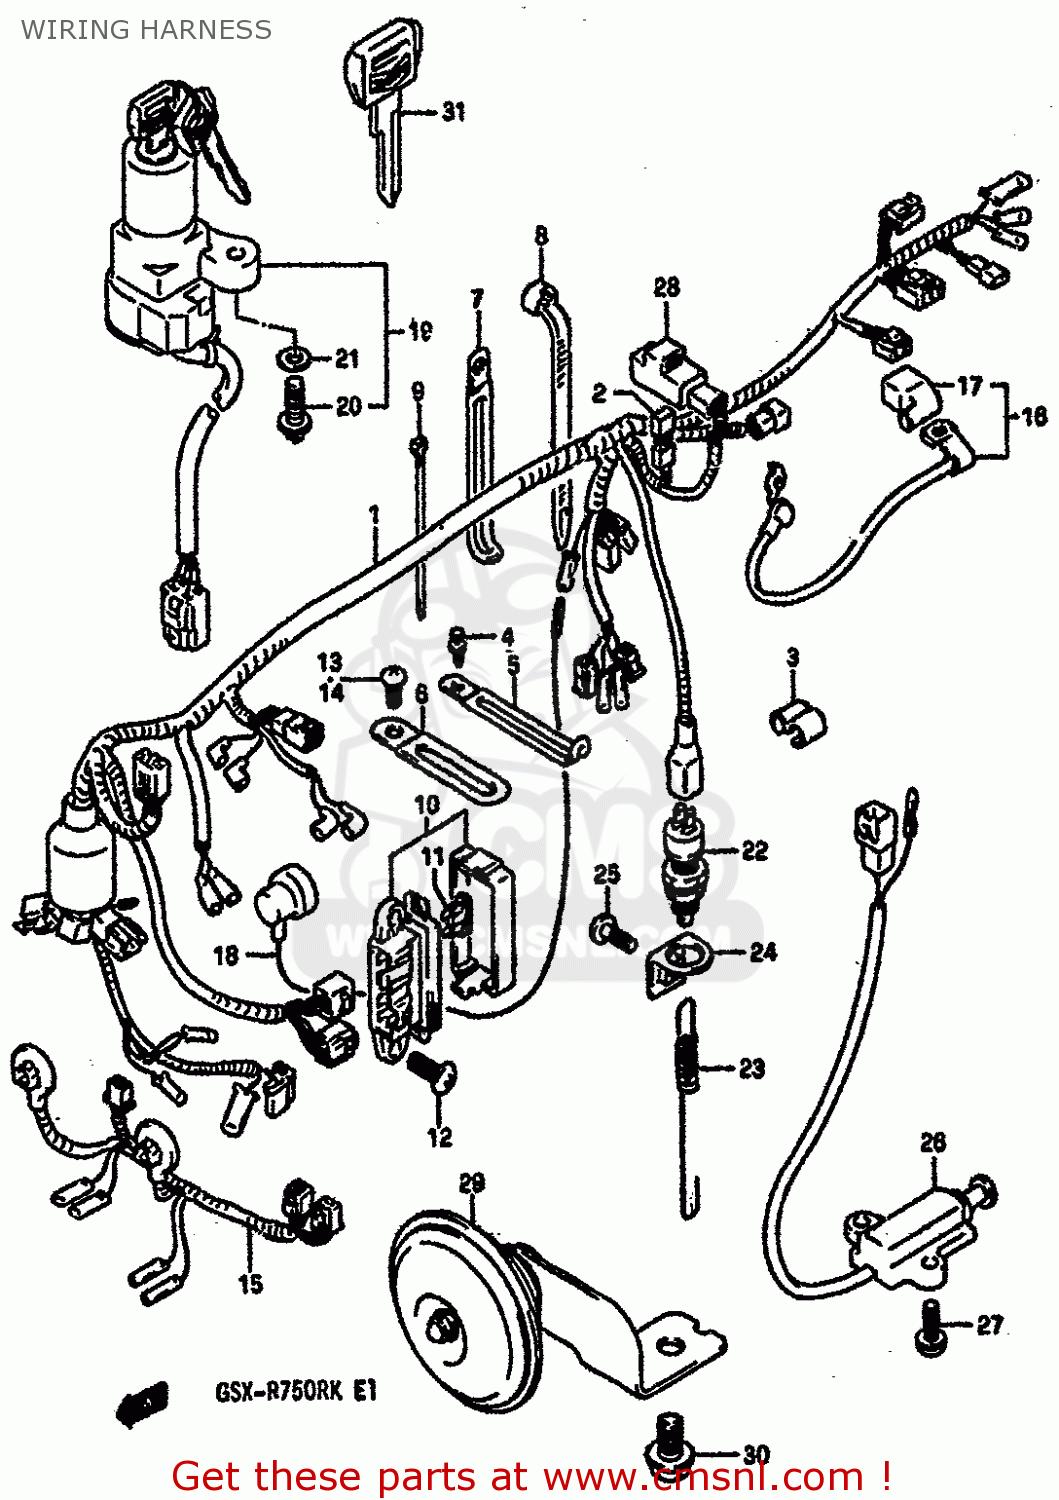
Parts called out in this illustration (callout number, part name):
1	HARNESS,WIRING
2	DIODE(STANLEY DE8804)
3	CLAMP
4	CLIP
5	CLAMP
6	CLAMP
7	CLAMP
8	CLAMP(L:125)
9	CLAMP
10	FUSE BOX ASSY
11	FUSE(10A)
12	SCREW
13	SCREW
14	SCREW
15	WIRE,HEADLAMP LEAD
16	LEAD WIRE,BATTERY PLUS
17	COVER,BATTERY TERMINAL
18	LEAD WIRE,OIL PRESSURE
19	LOCK ASSEMBLY,STEERING
20	SCREW(6X18)
21	WASHER
22	SWITCH ASSY,STOP LAMP
23	SPRING
24	BRACKET,STOP LAMP SWITCH
25	SCREW(6X12)
26	SWITCH ASSEMBLY,SIDE STAND
27	SCREW
28	RELAY ASSEMBLY
29	HORN ASSEMBLY
30	BOLT 8X12
31	KEY,BLANK
